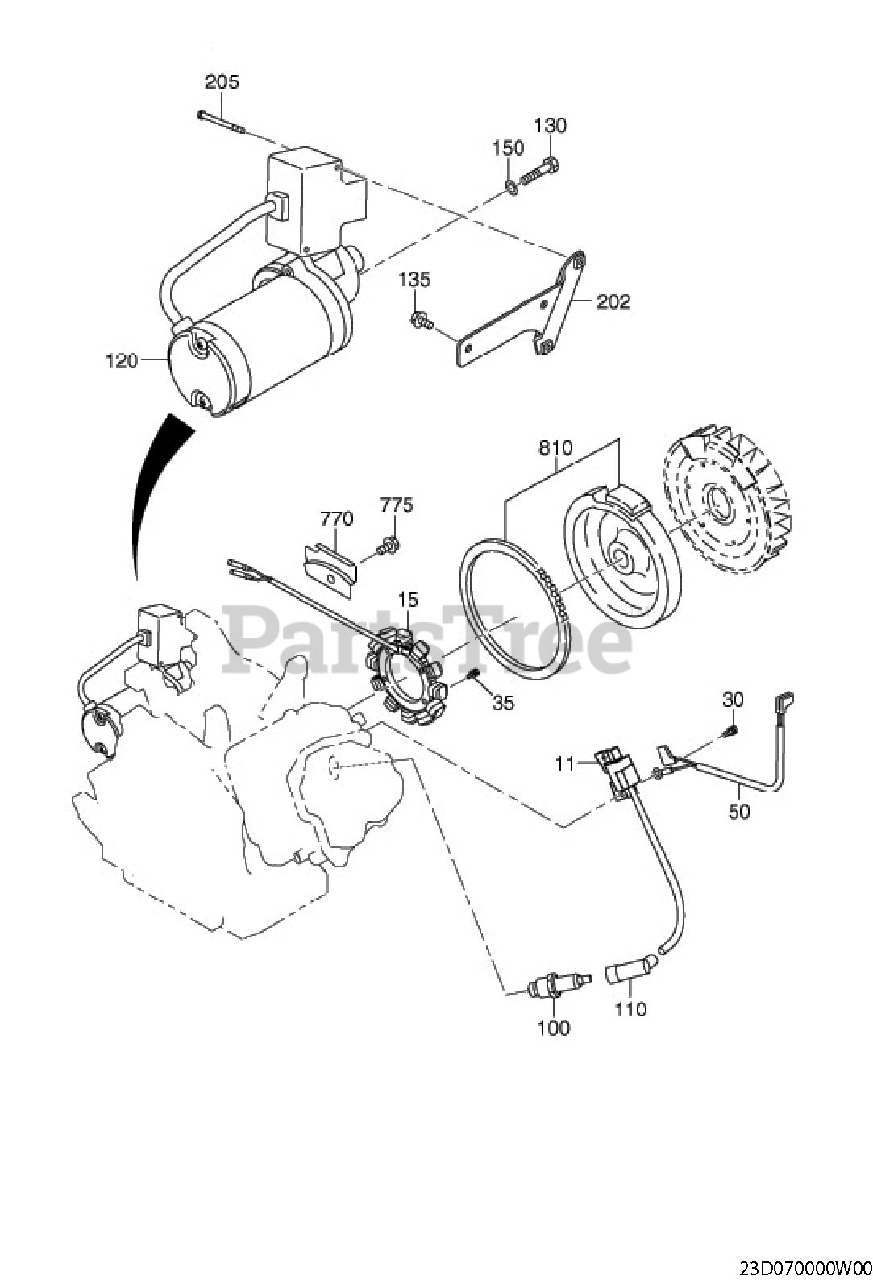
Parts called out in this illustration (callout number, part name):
11	IGNITION COIL
15	LAMP COIL CP
30	BOLT AND WASHER
35	SCREW AND WASHER
50	WIRE 11 CP
100	SPARK PLUG
110	SPARK PLUG CAP
120	STARTING MOTOR AY
130	BOLT CP, STARTER
135	FLANGE BOLT
150	WASHER
202	BRACKET(CONT. BOX) CP
205	SCREW AND WASHER AY
775	TAPPING BOLT
810	FLYWHEEL CP
